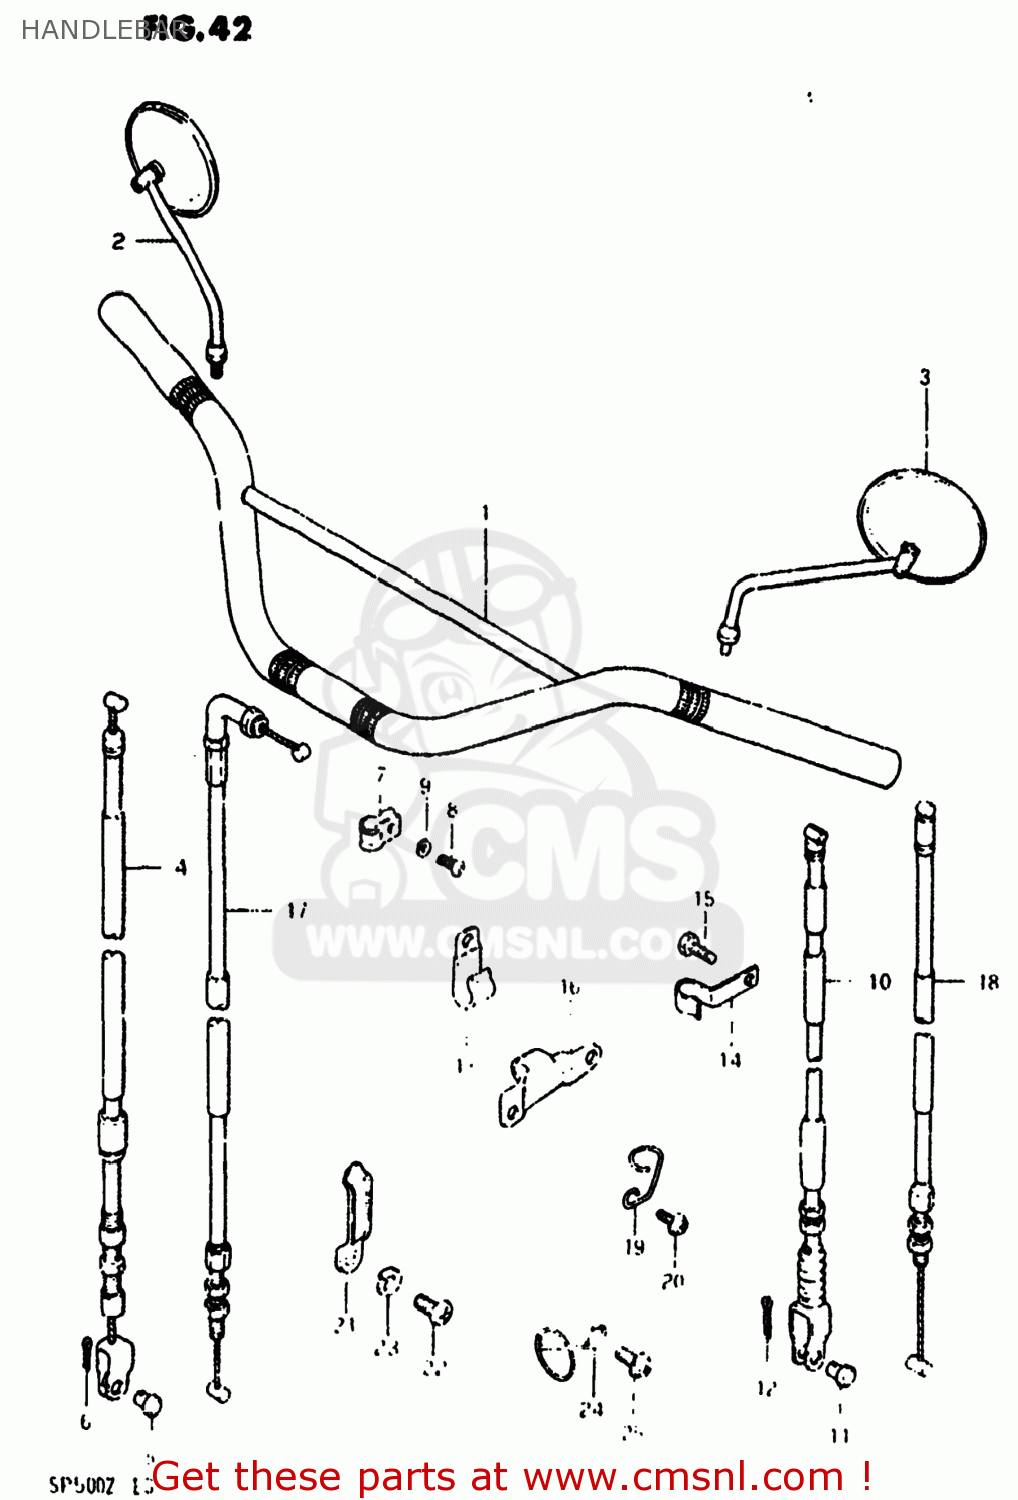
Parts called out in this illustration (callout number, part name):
1	HANDLEBAR
2	MIRROR ASSEMBLY,RIGHT
3	MIRROR ASSEMBLY,LEFT
4	CABLE ASSEMBLY,FRONT BRAKE
5	PIN(L:17.5)
6	PIN
7	GUIDE,CABLE
8	SCREW
9	LOCK WASHER
10	CABLE ASSEMBLY,CLUTCH
11	PIN(L:15)
12	PIN
13	CLAMP
14	CLAMP,CLUTCH CABLE NO.1
15	BOLT
16	STOPPER,CLUTCH CABLE
17	CABLE ASSY,THROTTLE
18	CABLE ASSY,DECOMP
19	GUIDE
20	SCREW
21	CLAMP
22	SCREW
23	LOCK WASHER
24	GUIDE,CABLE
25	SCREW
